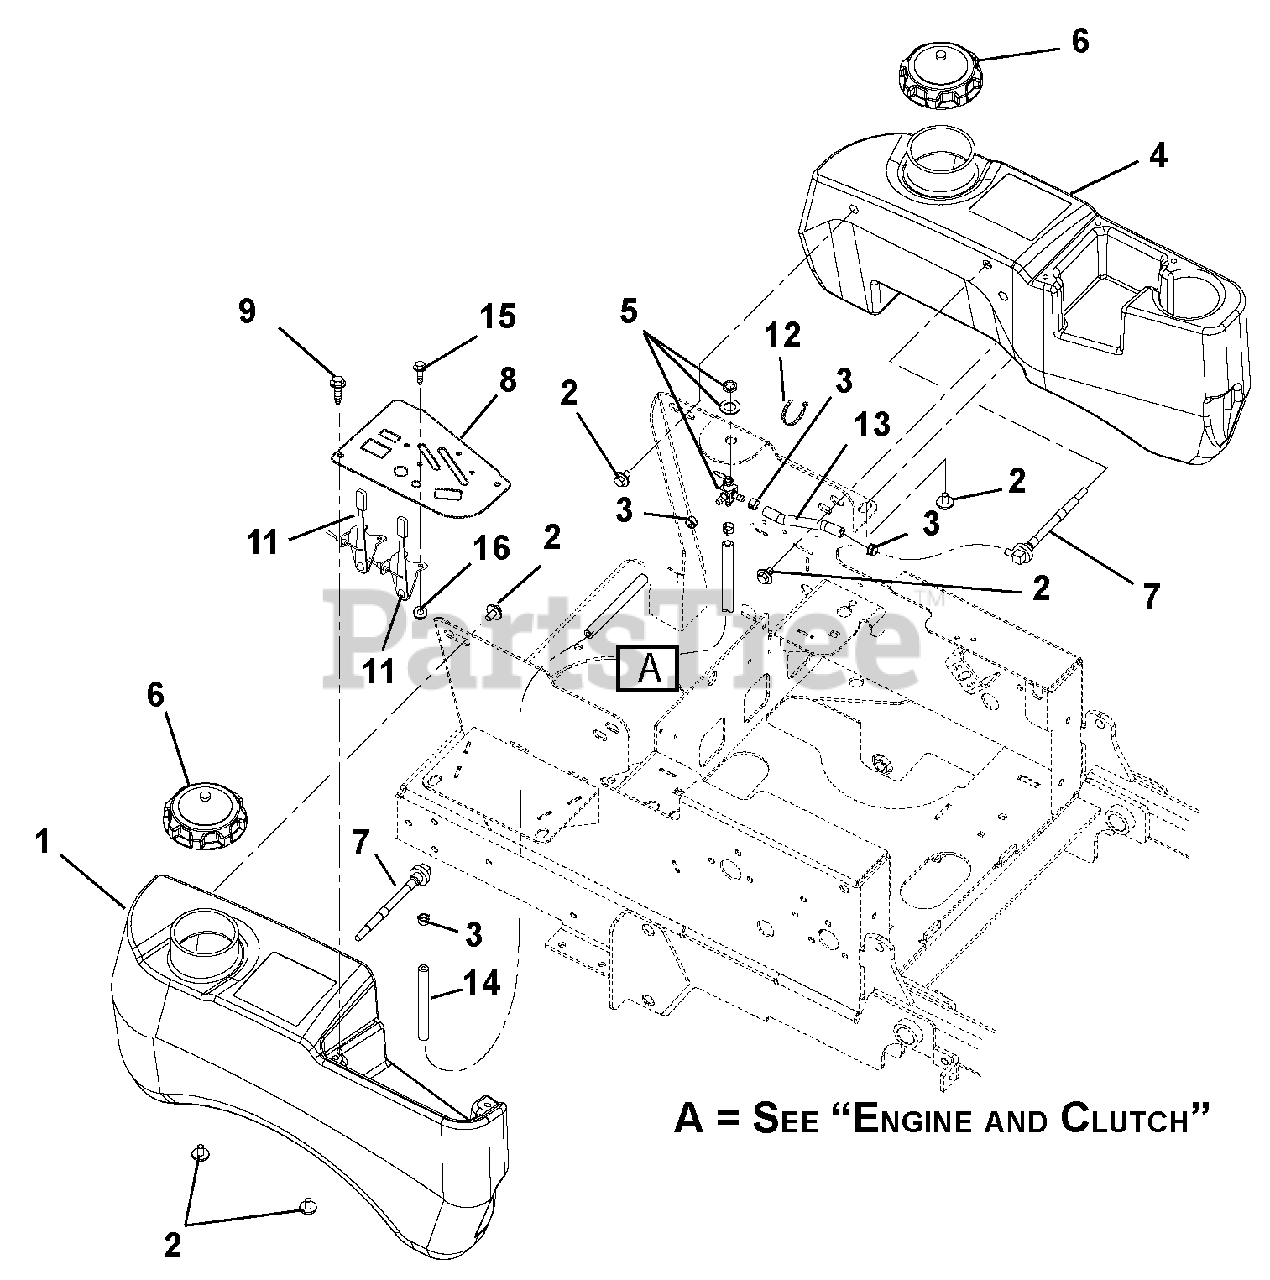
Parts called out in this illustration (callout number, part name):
1	Tank, Fuel Right Hand
2	Bolt, SEMS .31-18 x .62
3	Clamp, Fuel Line
4	Tank, Fuel Left Hand
5	Valve, Fuel
6	Cap, Fuel Non-Vent Autolock (991106)
7	Assembly, Tank Fuel Pick-up
8	Panel, Control
9	Screw, Machine 10-24 x .50 Stainless
10	Cable, Throttle
11	Cable, Control
12	Cable Tie
13	Hose, .25 Low-PERM Bulk Gas
14	Hose, .25 Low-PERM Bulk Gas
15	Screw, Machine 10-24 x .50 Hex Washer Head
16	Nut, Locking-Nylon 10-24 with Insert
